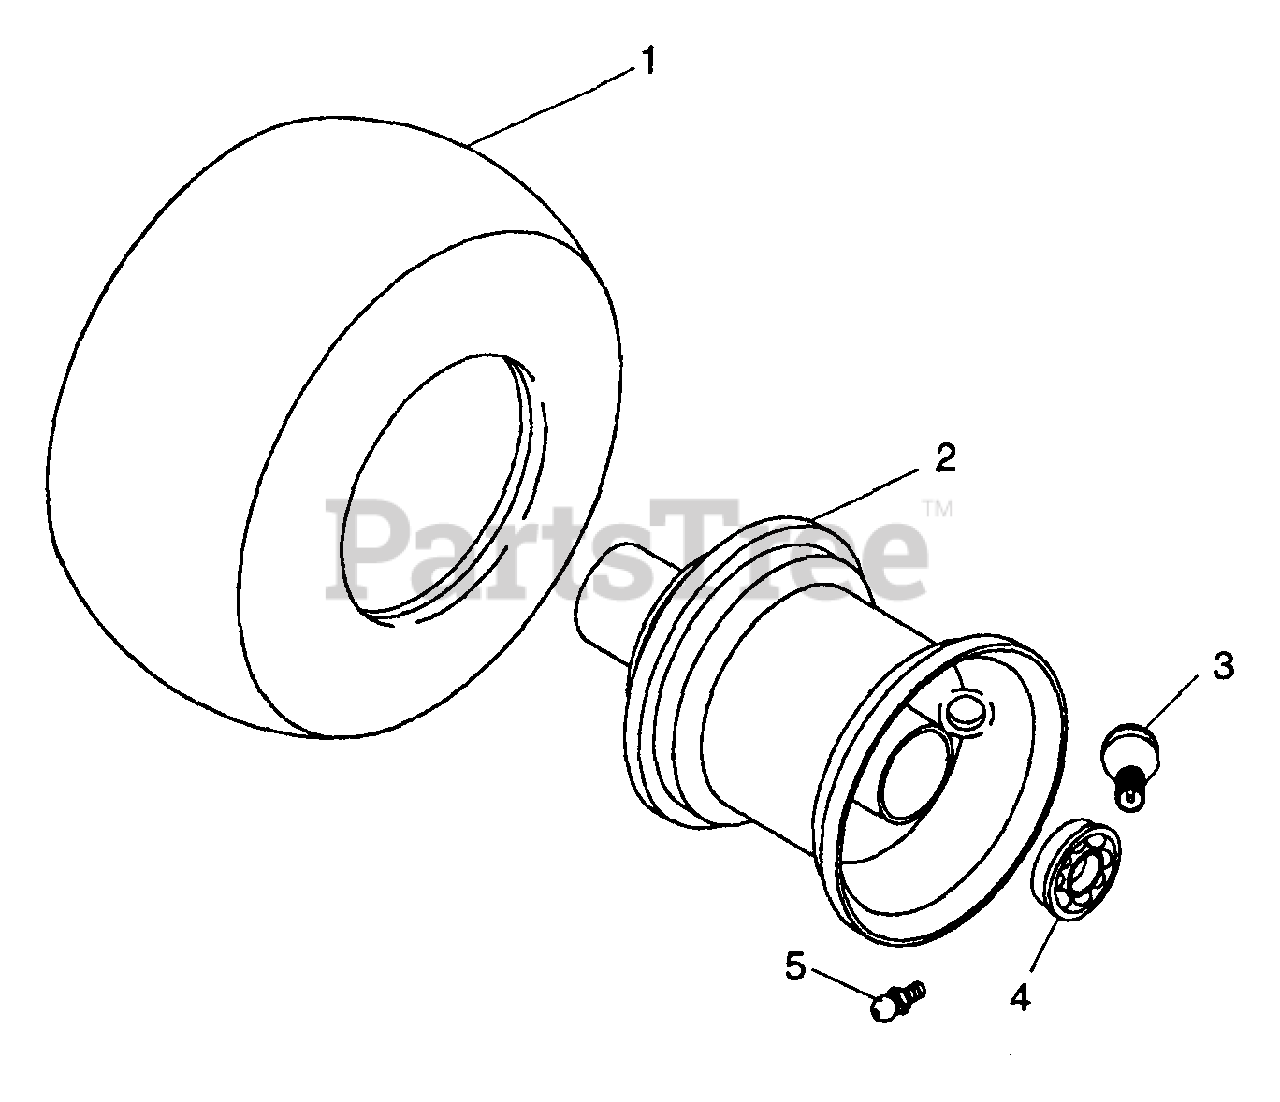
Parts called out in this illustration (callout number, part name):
1	Tire 13 x 6.50-6
2	Rim-Assembly 4.5 x 3.75
3	Valve Stem Assembly
4	Radial Bearing
5	Fitting-Lube .25-28 x .256
